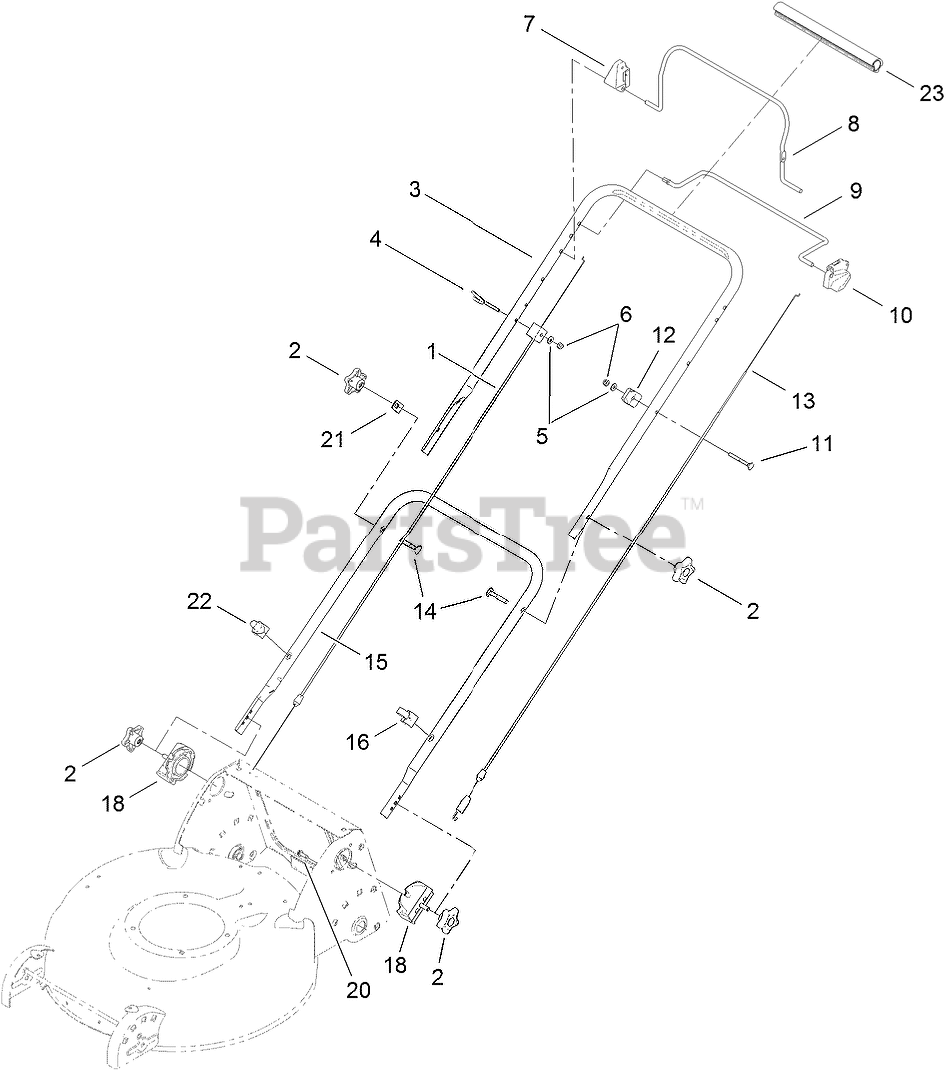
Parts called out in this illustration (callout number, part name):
1	Cable-Brake
2	KNOB-HANDLE
3	Handle-Upper
4	GUIDE-ROPE
5	WASHER-FLAT
6	NUT-LOCK, NI
7	STOP-PIVOT
8	Bail-Brake
9	Bail-Control
10	Stop-Pivot
11	SCREW
12	ANCHOR-CABLE, UPPER
13	CABLE-TRACTION
14	SCREW-HANDLE
15	HANDLE-LOWER
16	GUIDE-CABLE
18	HANDLE MOUNT ASM
20	SCREW-HWHTF
21	CLAMP-R
22	GUIDE-ROPE, LOWER
23	GRIP-HANDLE, COMFORT
